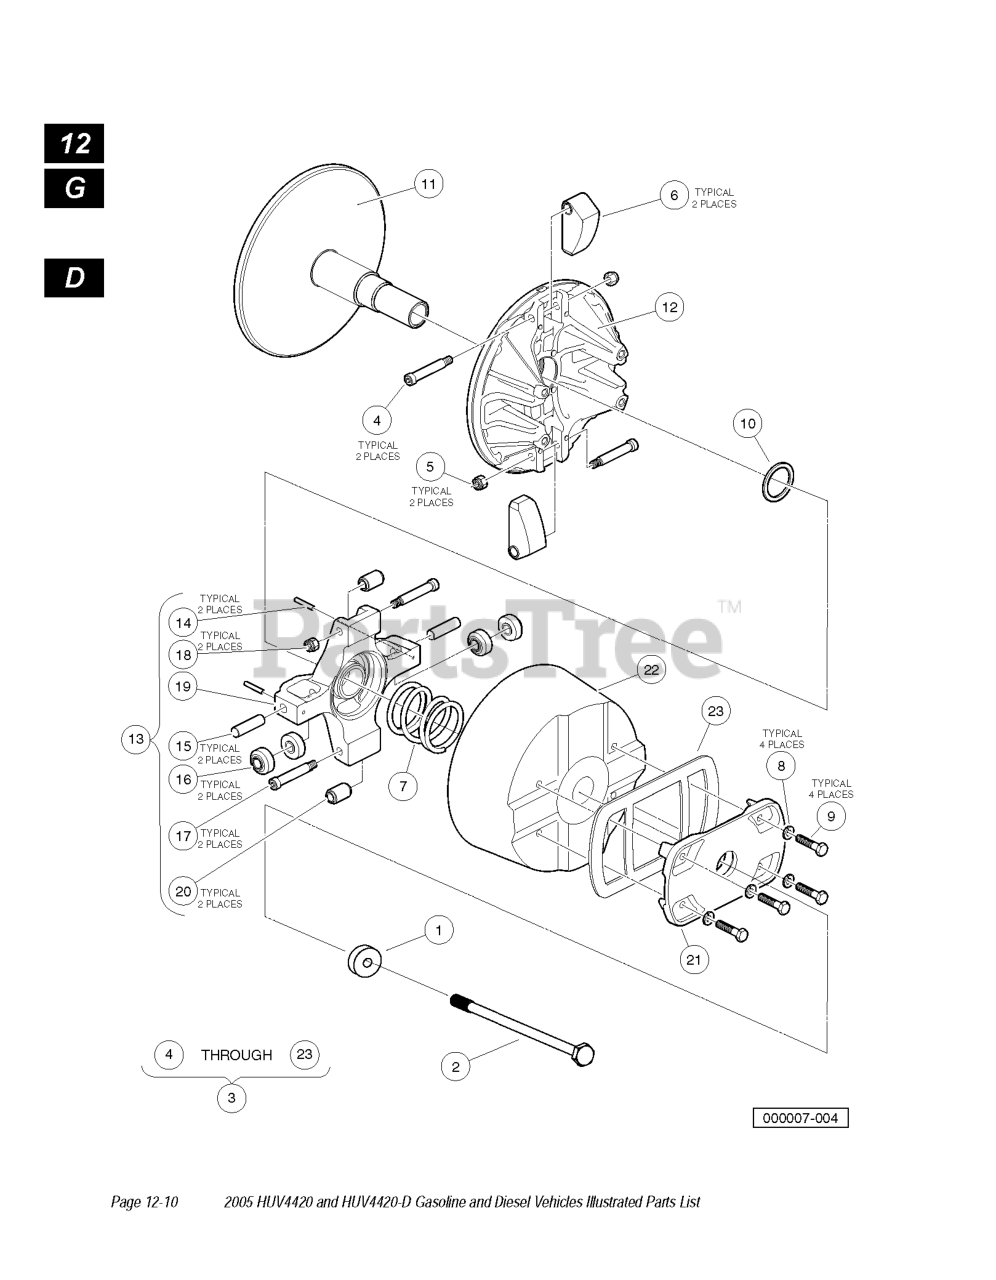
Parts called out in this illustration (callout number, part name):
1	WASHER, STEPPED, CVT PRIMARY
2	BOLT, M10X1.5X160
3	CLUTCH, 4X4, DIESEL, W/COVER
4	SCREW, SHLDER HEX, .312 X 1.75
5	NUT, LOCK HEX, 1/14-20, FLEXLC
6	SUB ASSY, WT CLUTCH, DIESEL
7	SPRING, COMPRESSION, PRIMARY
8	WASHER, LOCK, H SPRING, 1/4
9	SCREW, CAP, HEX HD, 1/4 X 1.25
10	SHIM, 1.63 X 1.33
14	PIN, SPRING SLOTTED,1.25 X 1.0
15	PIN, DOWEL, .375 X 1.50
16	ROLLER, TORQUE, DIESEL
17	SCREW, SHLDER HEX, .312 X 1.75
18	NUT, LOCK HEX, 1/14-20, FLEXLC
20	SUB ASSY, ROLLER WEIGHT
22	COVER, CLUTCH, 4X4
23	GASKET, COVER, CLUTCH, 4X4
